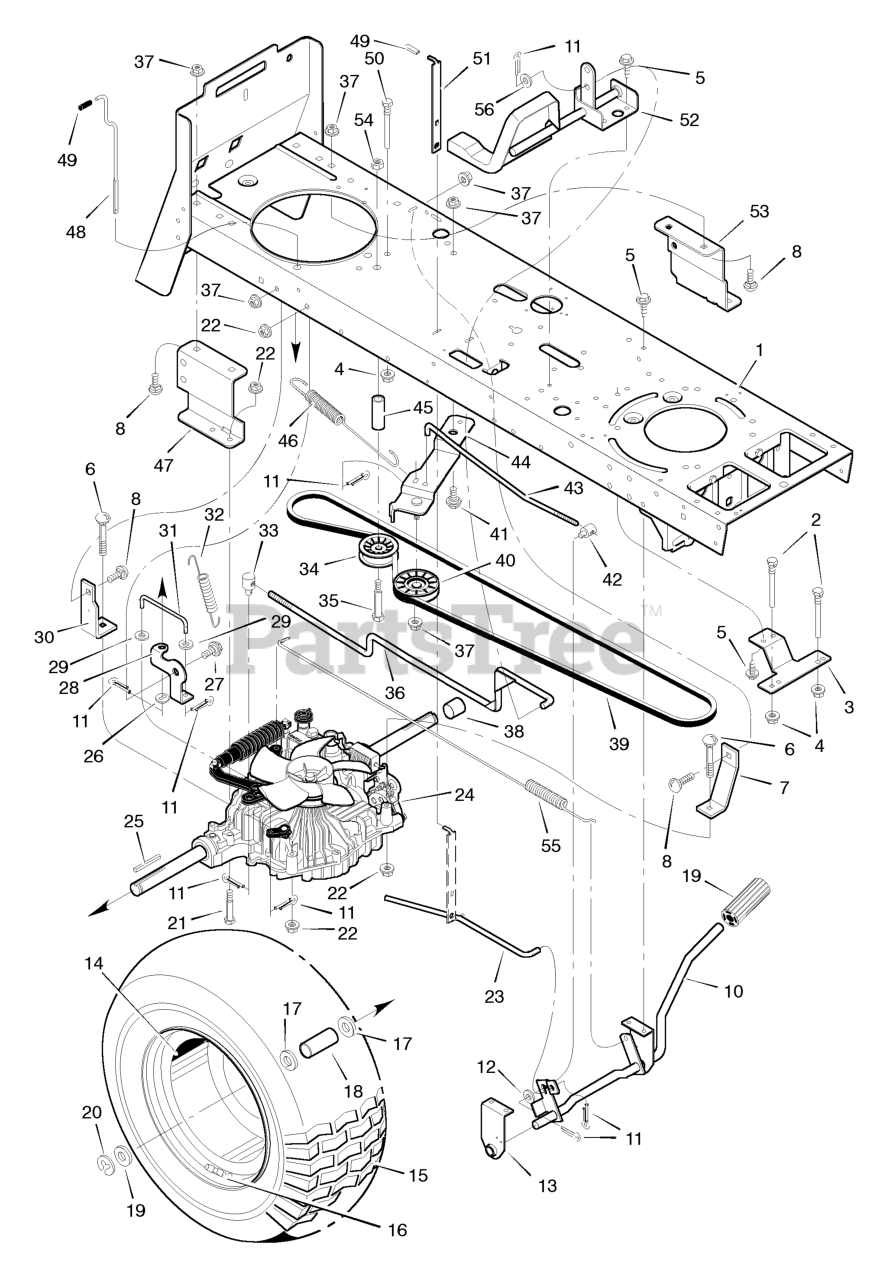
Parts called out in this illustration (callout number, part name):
1	Frame Assembly
2	SCREW, Guide
3	Bracket, Belt Guide
4	NUT, Hex Flange, 5/16-18
5	CAPSCREW, Hex Head, 5/16-18 x 3/4
6	Bolt, Carriage
7	Bracket, Torque
8	Bolt, Carriage
9	PEDAL, Clutch and Brake
10	Lever Assembly, Pedal
11	COTTERPIN, 3/4
12	Washer
13	Bracket, Pedal Support
14	Assembly, Wheel and Tire
15	Tire Only *
16	VALVE STEM & CAP
17	Washer
18	Spacer
19	WASHER, 1-1.3 16G FLT
20	E-RING, Retainer
21	BOLT, Hex, 5/16-18 x 2-1/2
22	NUT, Hex Flange, Center Lock, 5/16-18
23	Rod, Latch
24	Transaxle
25	Key, Square
27	BOLT, Shoulder, 3/8-16 x 3/5
28	Bracket, Dump Valve
29	WASHER, FLAT
30	Bracket, Torque
31	Rod, Dump Valve
32	Spring, Extension
33	NUT, Adjusting, 1/2-13
34	Pulley, Backside Idler
35	Shoulder Bolt
36	Rod, Control
37	NUT, Hex Flange, Center Lock, 3/8-16
38	Spacer
40	PULLEY, V-IDLER 3-
41	BOLT, Shoulder, 3/8-16 x 1/2
42	NUT, Adjusting
43	Rod, Clutch
44	Bracket, Idler
45	Spacer
46	Spring, Extension
47	Screw-Slotted
48	Rod, Dump Valve
50	SCREW, Guide, 5/16-18
51	Lever, Parking Brake
52	Pedal Assembly
53	Screw-Sem
54	NUT, Lock, 1/2-13
56	Washer
